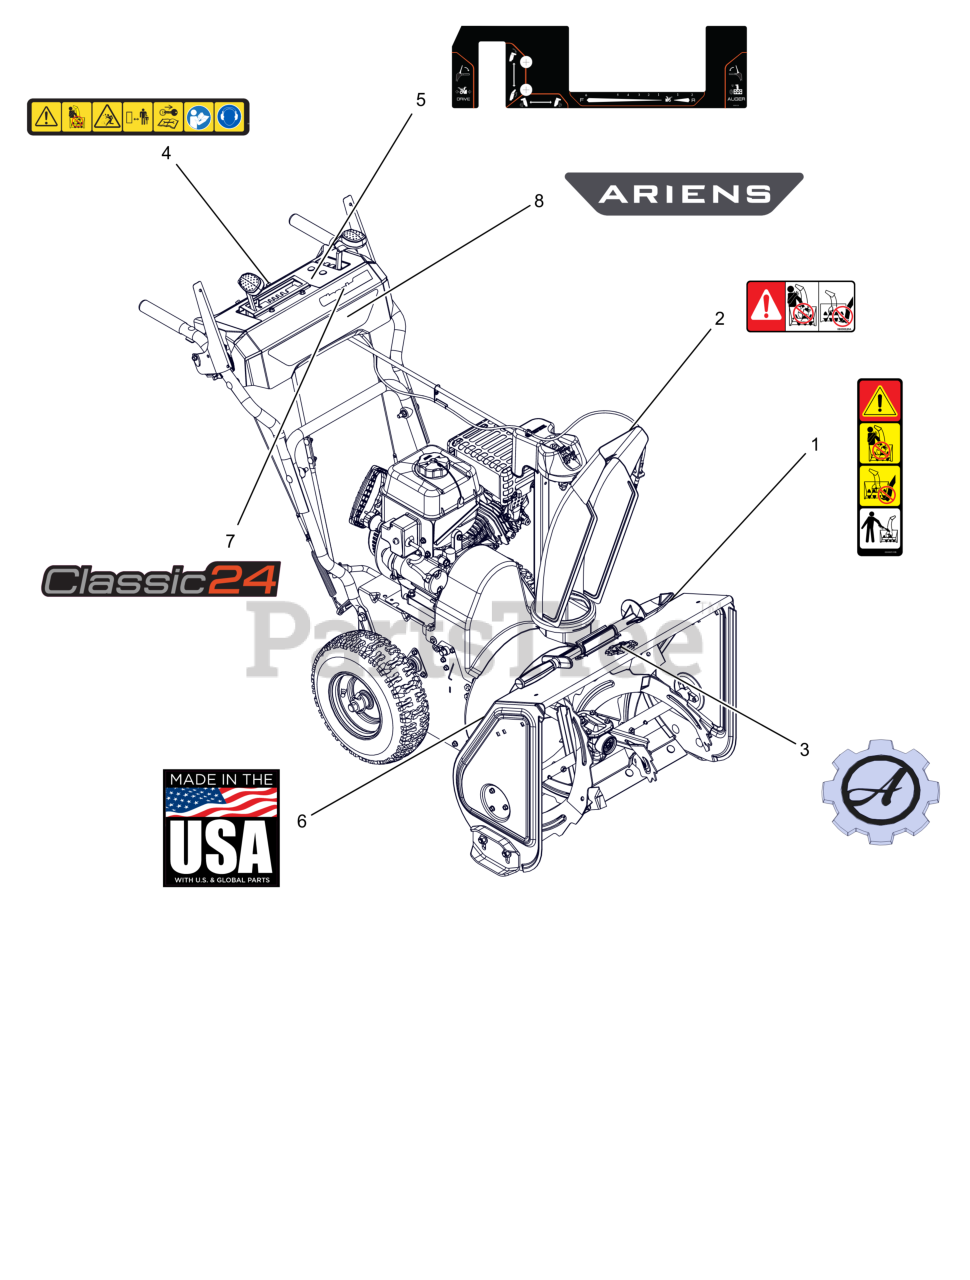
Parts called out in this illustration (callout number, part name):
1	DECAL, DANGER - ROTATING PARTS
2	DECAL, DANGER
3	DECAL, ARIENS-GEAR BADGE -THK
4	DECAL,DASH - SAFETY
5	DECAL,CONTROL-COMP REMOTE
6	DECAL, MADE IN USA
7	DECAL, DASH - CLASSIC 24
8	DECAL, DASH BRAND - ARIENS PB
